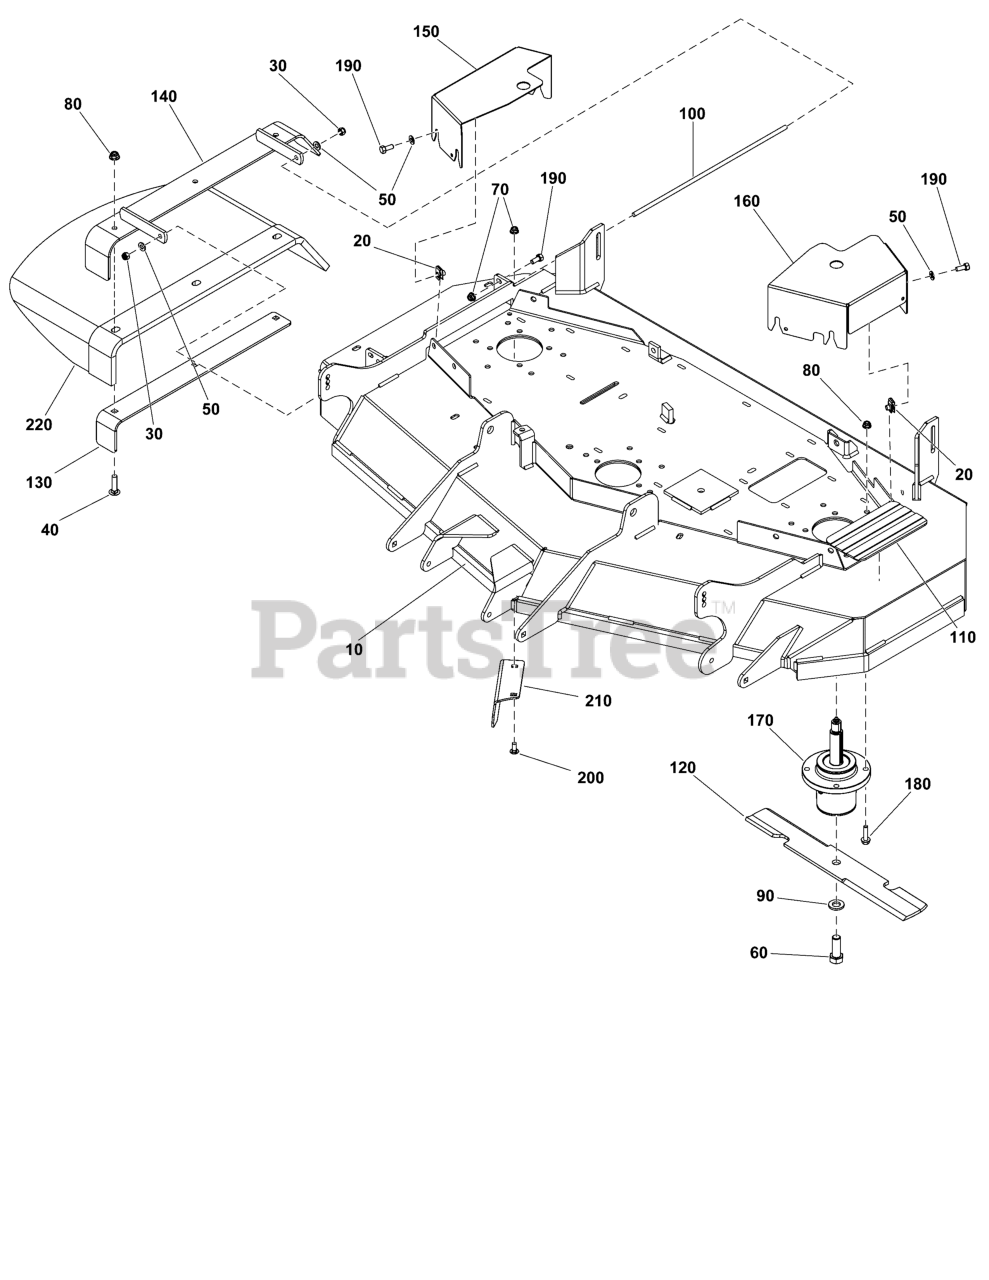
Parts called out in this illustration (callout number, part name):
10	DECK SHELL W/DECALS, 800-52 (5422959B)
10	DECK SHELL W/DECALS, 800-52 AUS 5422959B
20	BODY CLIP, 5/16-18 X
30	NUT, 5/16-24 HEX NYLO
40	BOLT, 3/8-16 X 1-1/2
50	WASHER
60	BOLT
70	NUT
80	NUT, 3/8-16 HEX NYLOCK
90	WASHER, 5/8" YZ
100	ROD
110	SAFETY WALK
120	BLADE, 18 X .25 X 2.5, 1 X 3.5 (SET OF THREE)
140	KIT-MOUNTING PLATE, CHUTE ROTATION
150	GUARD, PULLEY
160	GUARD, PULLEY
170	ASSM, SPINDLE, LONG S
190	BOLT, 5/16-18 X 3/4"
200	BOLT, 5/16-18 X 3/4",
210	DEFLECTOR
220	CHUTE, RUBBER DISCHARGE (5104442)
